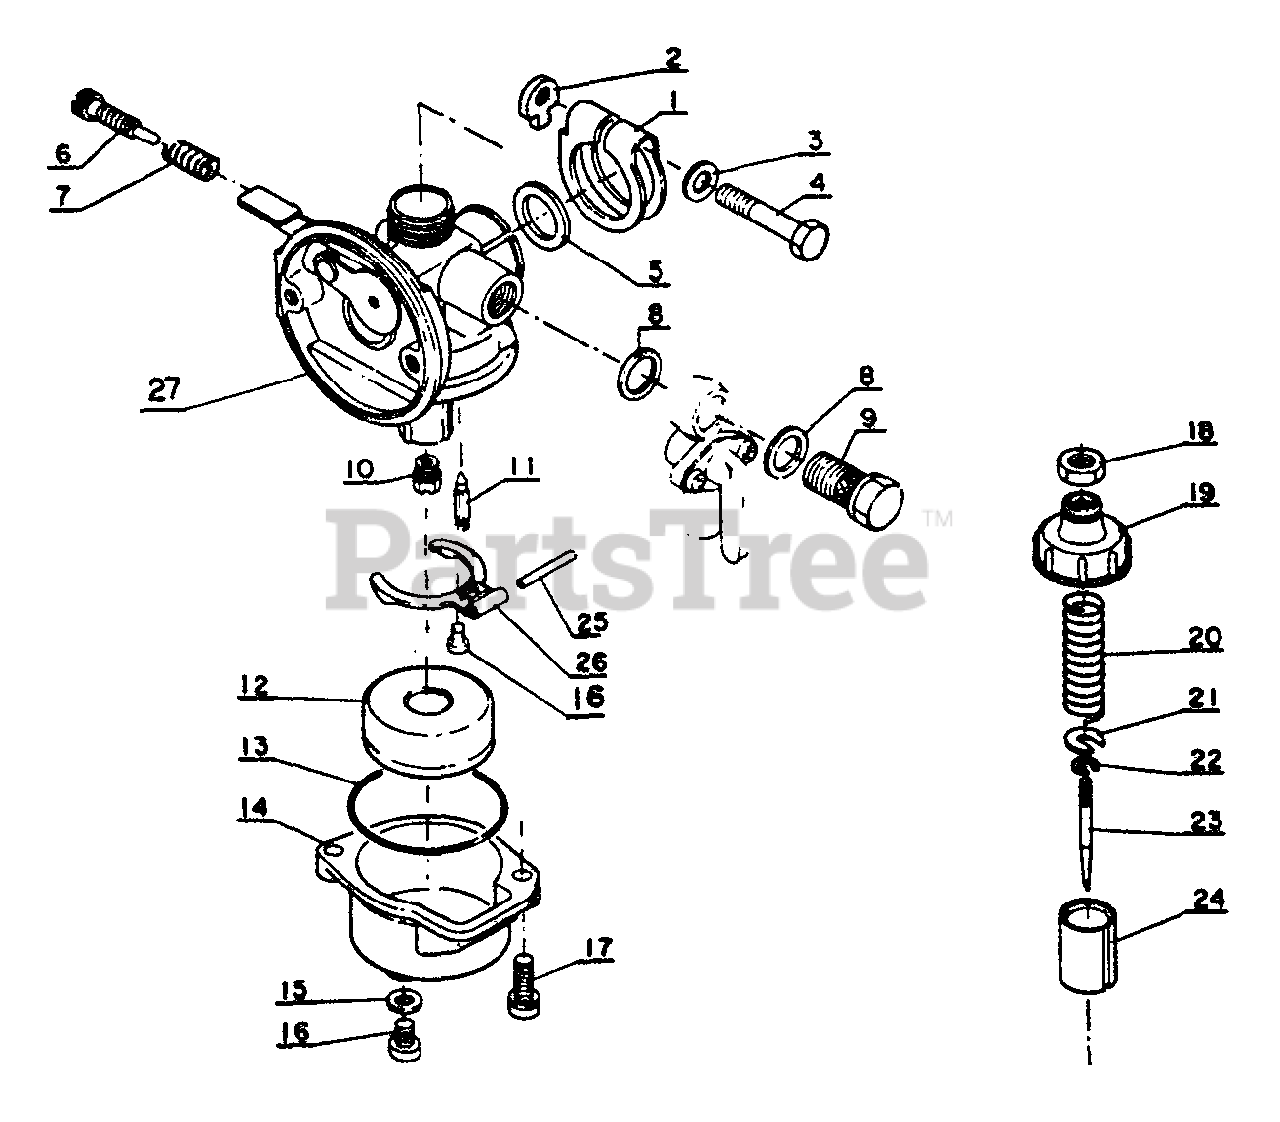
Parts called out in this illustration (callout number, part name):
1	CLAMP
2	NUT
3	WASHER - 5
4	BOLT
6	SCREW, IDLE ADJUST
7	SPRING, IDLE ADJUST
9	BOLT, BANJO
10	VALVE, MIXTURE
11	VALVE, INLET NEEDLE
12	FLOAT
13	O-RING
14	CHAMBER, FLOAT
15	GASKET, DRAIN
16	SCREW - 4X6
17	SCREW - 4X12
18	NUT
19	COVER - TOP
20	SPRING, THROTTLE
21	SEAT, SPRING
22	RING, RETAINING
23	NEEDLE JET KIT
24	VALVE, THROTTLE
25	PIN, METERING LEVER
26	LEVER, METERING
27	BODY, CARBURETOR
